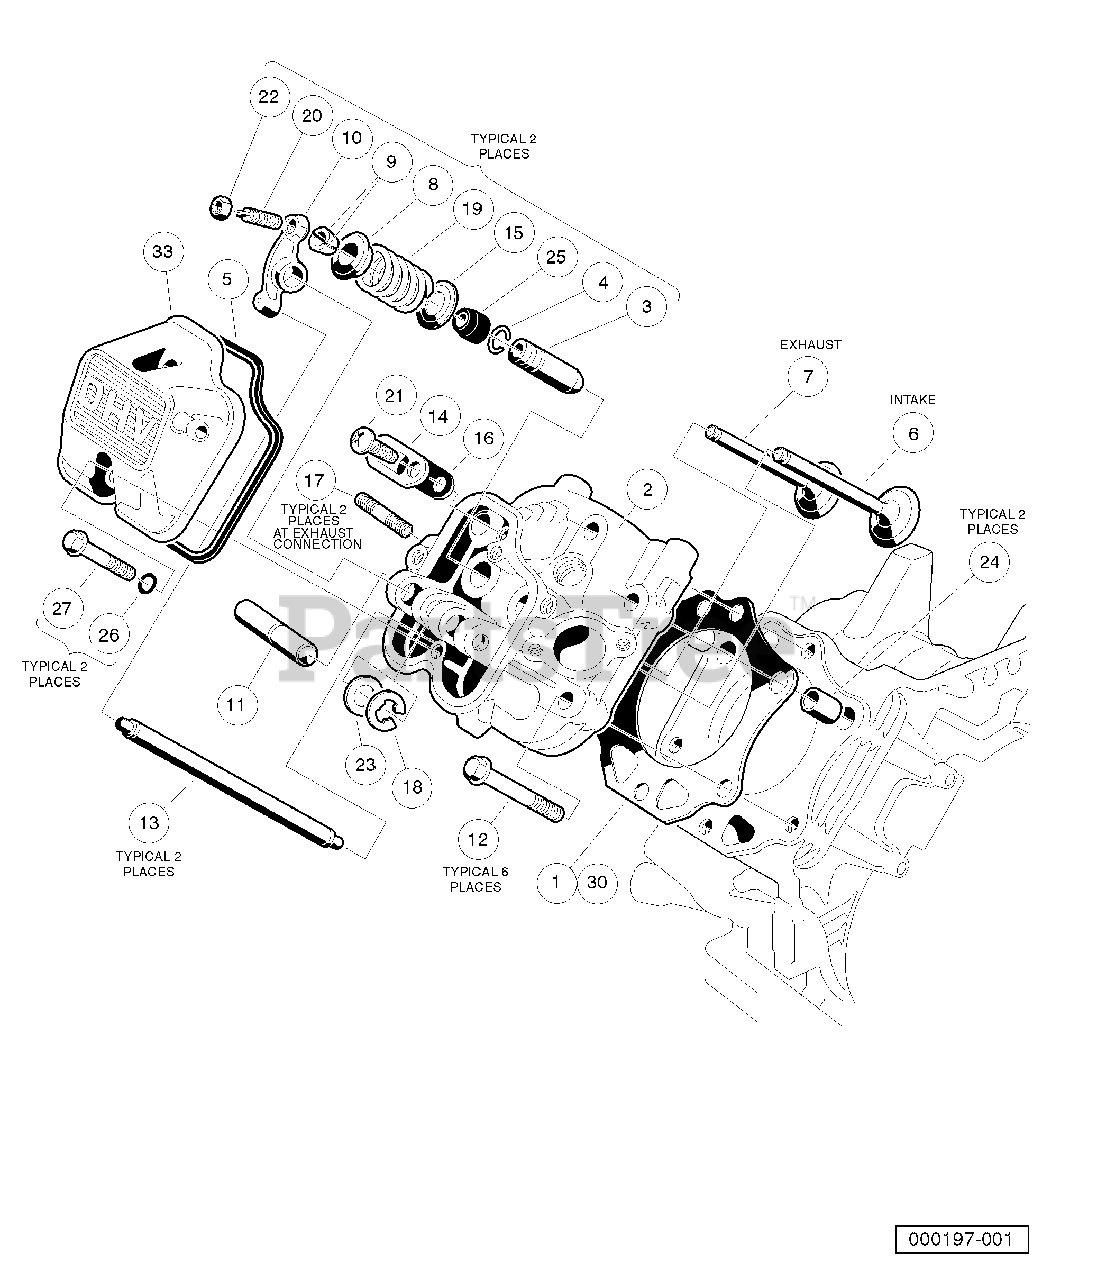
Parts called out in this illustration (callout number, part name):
1	Gasket, Head, FE290
2	Head Assembly, FE290 Cylinder
3	Guide, Valve, Intake
5	Gasket, Rocker Case
6	Valve, Intake
7	Valve, Exhaust
8	Retainer, Valve Spring
10	Arm, Rocker
11	Shaft, Rocker
12	Bolt, Flange Head, M8 x 1.25 x 45 mm
15	Seat, Spring
17	Stud, Two-Ended, M8-1.25
18	Circlip, Type-E
19	Spring, Engine Valve
23	Washer, 12.1x19x1.8
27	Bolt, 6x35
28	Kit, Gasket, FE290
29	Gasket, Exhaust
30	Gasket, Head, FE290
31	Gasket, Engine to Insulator
32	Gasket, Crankcase Cover
33	Case, Rocker -w/o Logo Fe290
